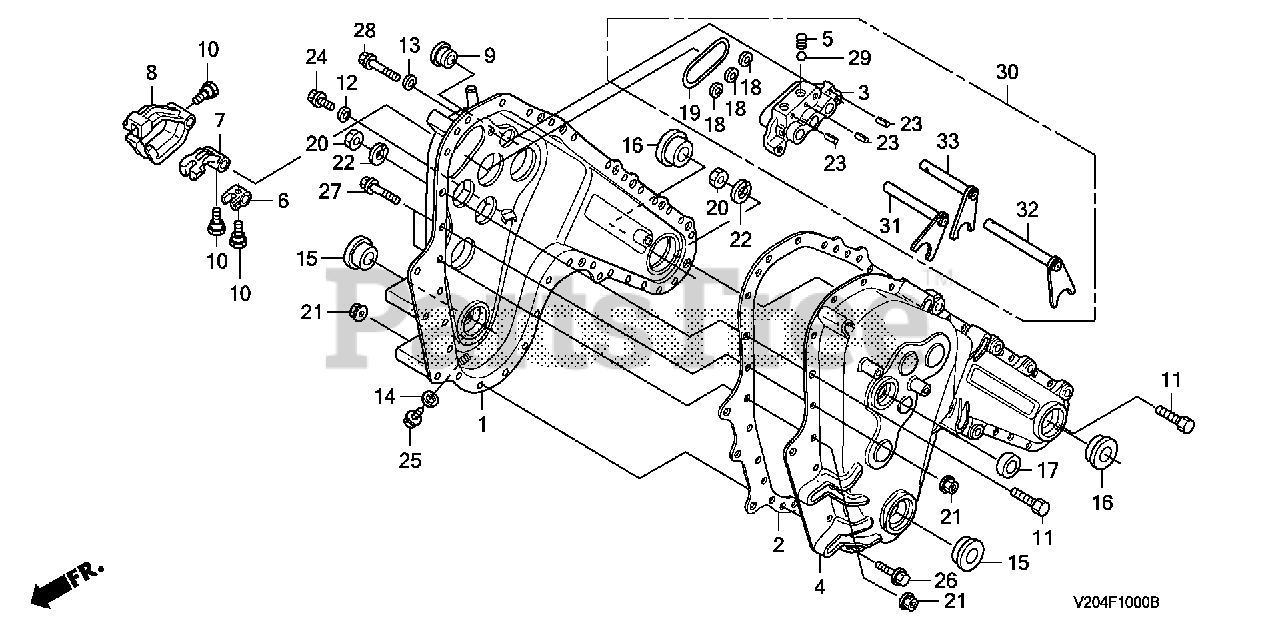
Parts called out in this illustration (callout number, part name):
1	CASE, R. TRANSMISSION
2	GASKET, TRANSMISSION CASE
3	HOLDER, SHIFT SHAFT
4	CASE, L. TRANSMISSION
5	SPRING, BALL SETTING
6	ARM, SECOND & THIRD CHANGE *NH105* (MAT BLACK)
7	ARM, FIRST & REVERSE CHANGE *NH105* (MAT BLACK)
8	ARM, ROTARY CHANGE *NH105* (MAT BLACK)
9	CAP, OIL HOLE
10	SCREW, FORK SETTING
11	BOLT, HEX. (10X17)
12	WASHER, SEALING (6MM)
13	WASHER, SEALING (8MM)
14	WASHER, SEALING (8MM)
15	OIL SEAL (25X47X13)
16	OIL SEAL (30X62X11)
17	OIL SEAL (17X35X7)
18	OIL SEAL (14X21.5X3)
20	NUT, HEX. (10MM)
21	NUT, FLANGE (8MM)
22	WASHER, SPRING (10MM)
23	PIN, SPRING (3X18)
24	BOLT, FLANGE (6X10)
25	BOLT, FLANGE (8X12)
26	BOLT, FLANGE (8X14)
27	BOLT, FLANGE (8X20)
28	BOLT, FLANGE (8X30)
29	BALL, STEEL (#10) (5/16)
30	HOLDER SUB-ASSY., SHIFT
31	SHAFT, SHIFT FORK (A)
32	SHAFT, SHIFT FORK (B)
33	SHAFT, P.T.O. CHANGE FORK
